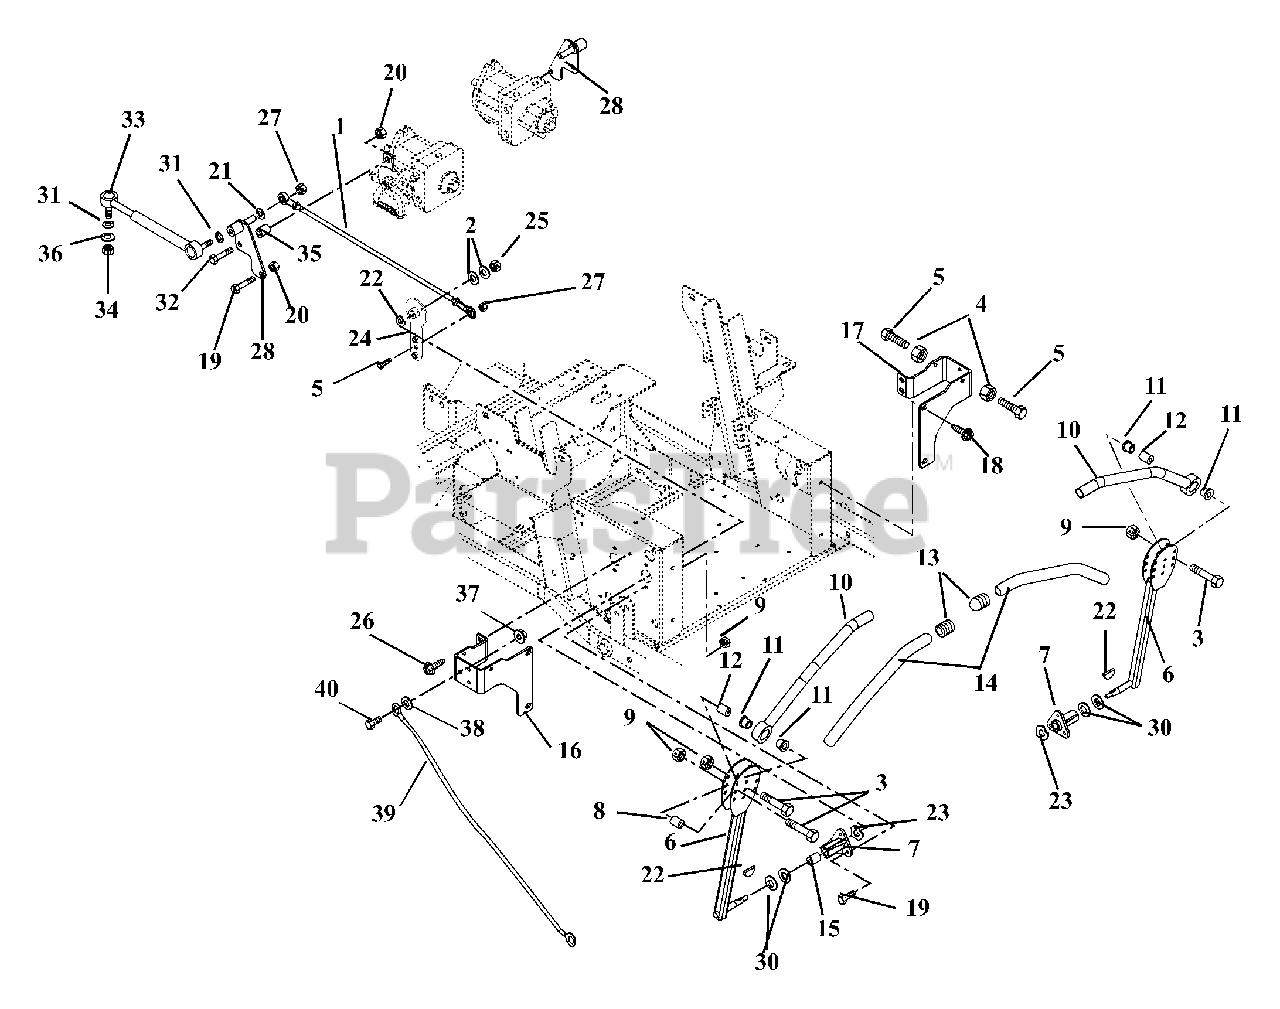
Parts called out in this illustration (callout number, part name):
1	ASSY,STEERING ROD .38RODX21.65
2	@WSHR-FL-STL.406X.812X.065 YWZ
3	@BLT-HEX .31-18X1.75 GR5 YWZC
4	NUT-HEX-JAM .375-16 YWZC
5	BLT-HEX .375-16X1.750 FTD YWZC
6	CONTROL ARM WELDMENT - BLACK
7	BUSHING, FLANGE
8	ECCENTRIC
9	@NUT-LK-TOP-FLG .31-18 YWZC
10	HANDLE WLDMT LH
11	BSHG-FLG .762X1.48X.44 NYL
12	SPACER .328 X .76 X 1.01
13	CAPLUG - HANDLEBAR
14	GRIP - HANDLEBAR
15	BSHG .625X.750X.500
16	RH STOP BRACKET - BLACK
17	LH STOP BRACKET - BLACK
18	@SCR-TAP .38-16X.75 HWH TR YWZ
19	@BLT-HEX .31-18X.75 GR5 YWZC
20	@NUT-LK-TOP-FLG .31-18 YWZC
21	@WSHR-LK .38X.094 REG YWZC
22	KEY-WDRF .13X.63 HRD#5
23	WAVE WASHER .640X.875X.125FH
24	WMT, PIVOT ARM
25	@NUT-LK-TOP-FLG .38-16 YWZC
26	@SCR-TAP .38-16X.50 HWH TR YWZ
27	@NUT-LK-CTR-JAM .375-16 YWZC
28	WMT, RTN/DAMPER/ROD END
29	@BLT-HEX .38-16X1.25 GR5 YWZC
30	WSHR-FL-STL .630X1.005X.062 YZ
31	@WSHR-LK .31X.078 REG YWZC
32	@BLT-HEX .31-18X1.25 GR5 YWZC
33	DAMPENER
34	@NUT-LK-NYL M8-1.25 YWZC
35	SPACER .318X.430X.375
36	@WSHR-FL-STL.38X.875X.083 YWZC
37	@NUT-LK-TOP-FLG .25-20 YWZC
38	WSHR-FL-STL .265X.50X.087YWZC
39	CBL,HOOD
40	@BLT-HEX .25-20X.75 GR5 YWZC
